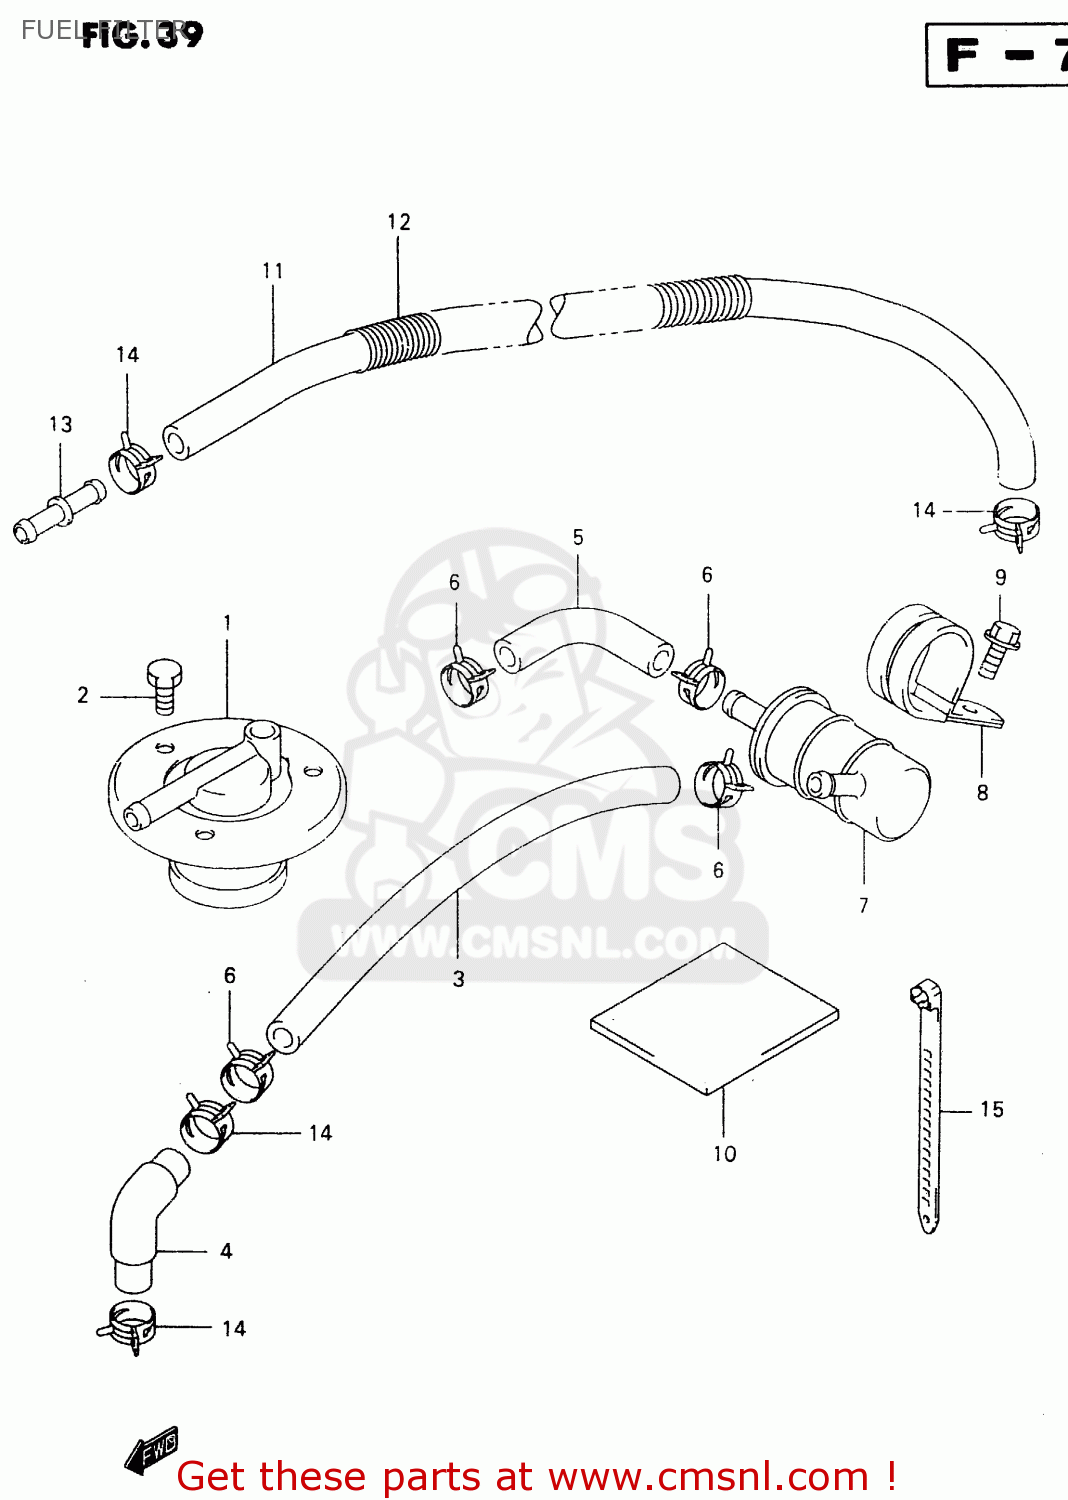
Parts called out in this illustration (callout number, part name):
1	VALVE,FUEL CUT
2	BOLT 5X10
3	HOSE(7X12X600)
4	JOINT,FUEL HOSE
5	HOSE,FUEL TANK & FILTER
6	CLIP
7	FILTER,FUEL
8	CLAMP,FUEL FILTER
9	BOLT
10	CUSHION,FILTER FITING
11	HOSE(7X12X600)
12	SPRING
13	JOINT
14	CLIP
15	CLAMP(L:165)
